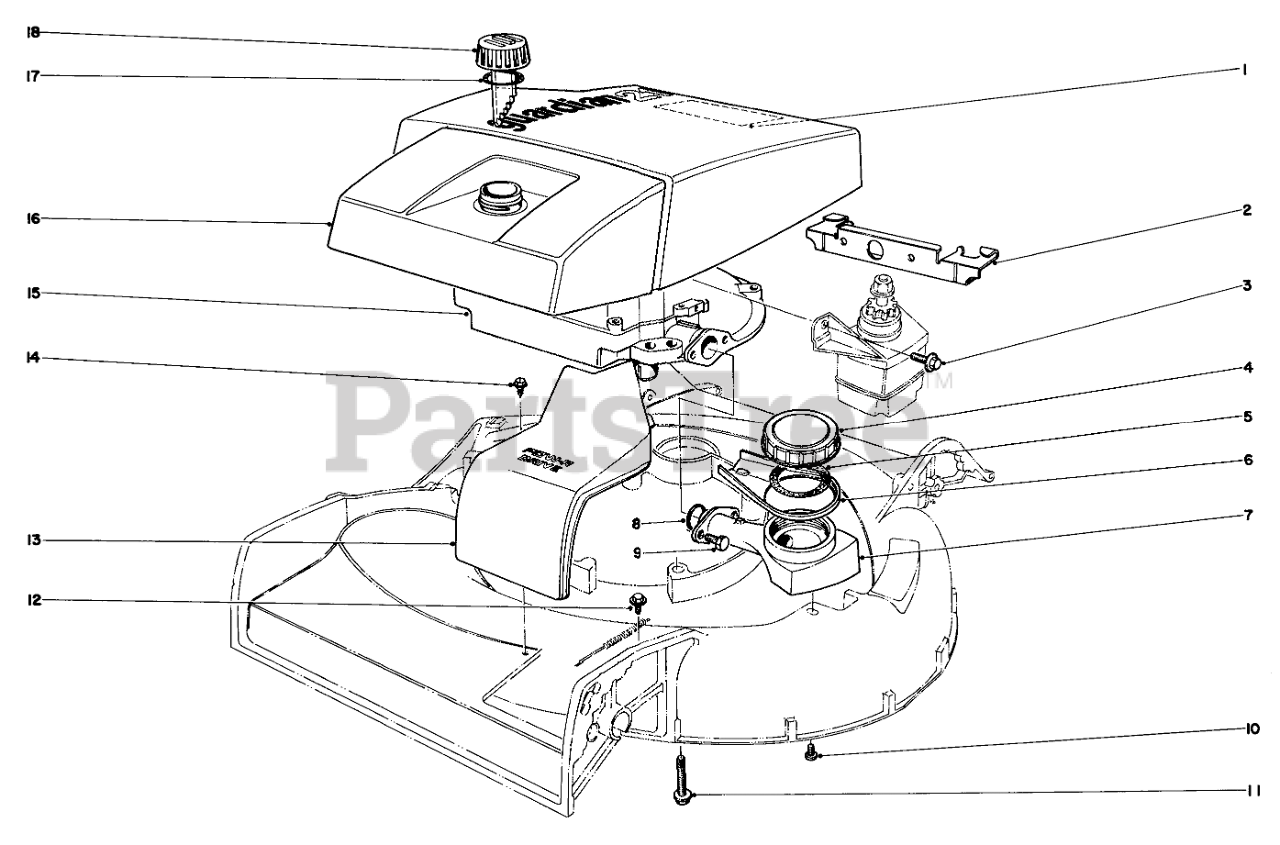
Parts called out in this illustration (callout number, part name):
1	Decal-Maintenance
2	Shroud Bracket
3	SCREW
4	Oil Gauge Cap
5	VISUAL OILER GASKET
6	Spout
7	Oil Gauge
8	O RING
9	SCREW-HH
10	Screw
11	3/8-16 X 2-3/4 CAPSCR
12	Screw
13	Cover
14	SCREW-HWHTF
15	Engine
16	Shroud
17	Gasket
18	Gas Cap
